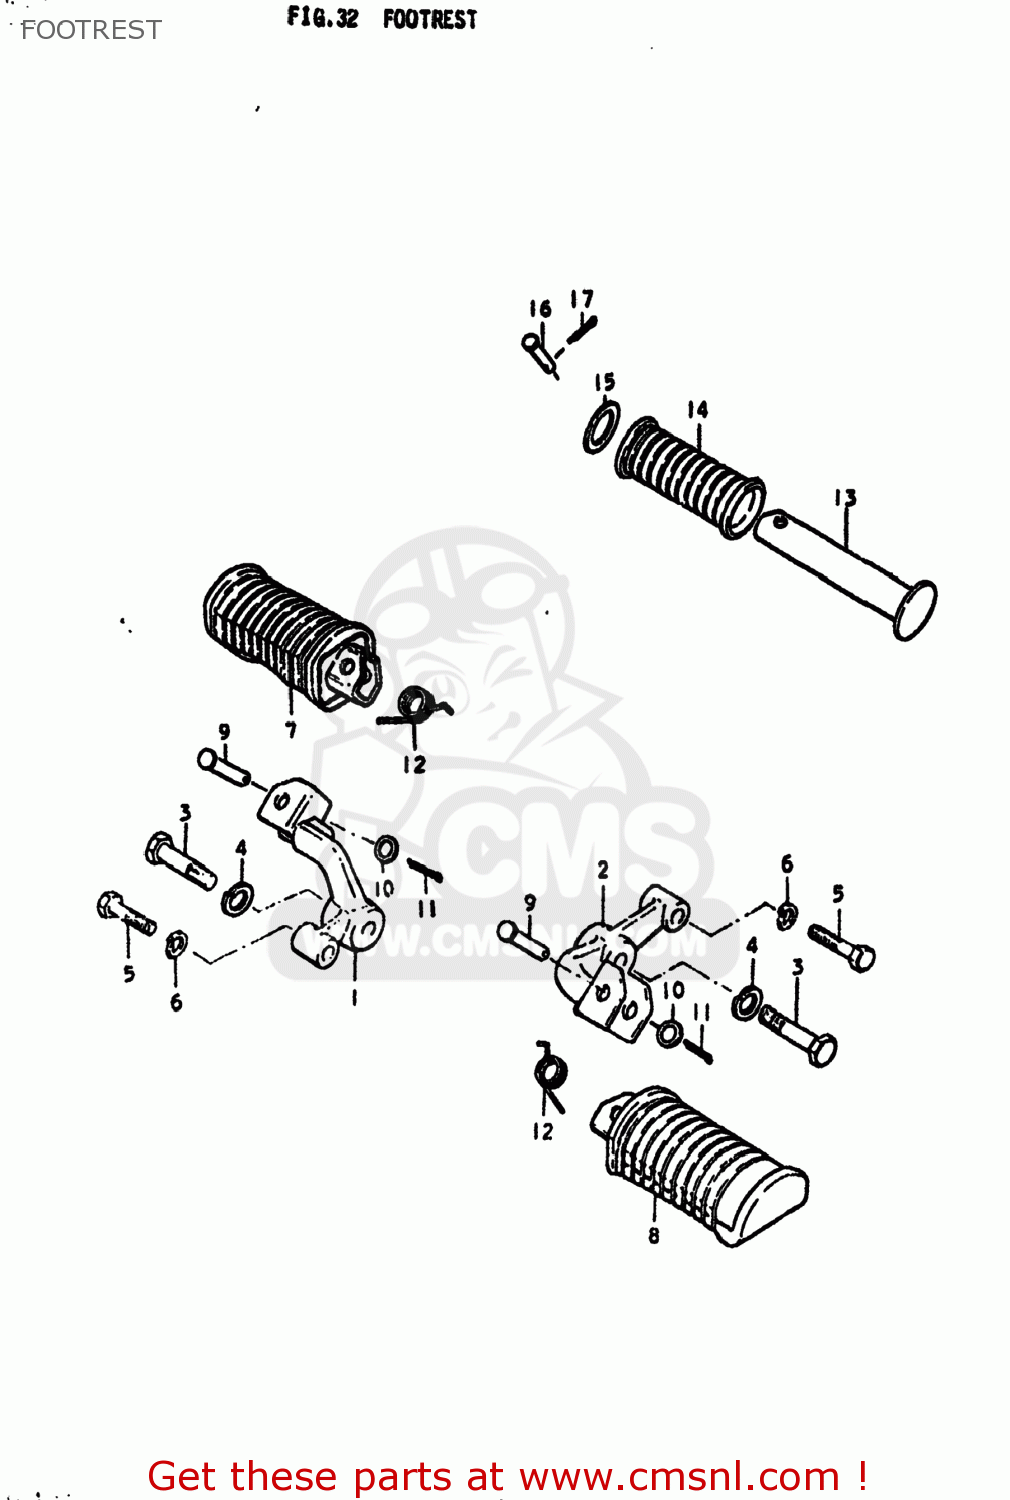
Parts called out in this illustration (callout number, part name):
1	BAR,FRONT FOOTREST
2	BAR,FRONT FOOTREST,LEFT
3	BOLT
4	LOCK WASHER
5	BOLT 8X40
6	LOCK WASHER
7	RUBBER,FRONT FOOTREST
8	FOOTREST
9	PIN
10	WASHER
11	PIN 20X20
12	SPRING
13	BAR,FOOTREST RUBBER
14	RUBBER,PILLION FOOTREST
15	WASHER (19.5X32X2)
16	PIN
17	PIN 20X20
